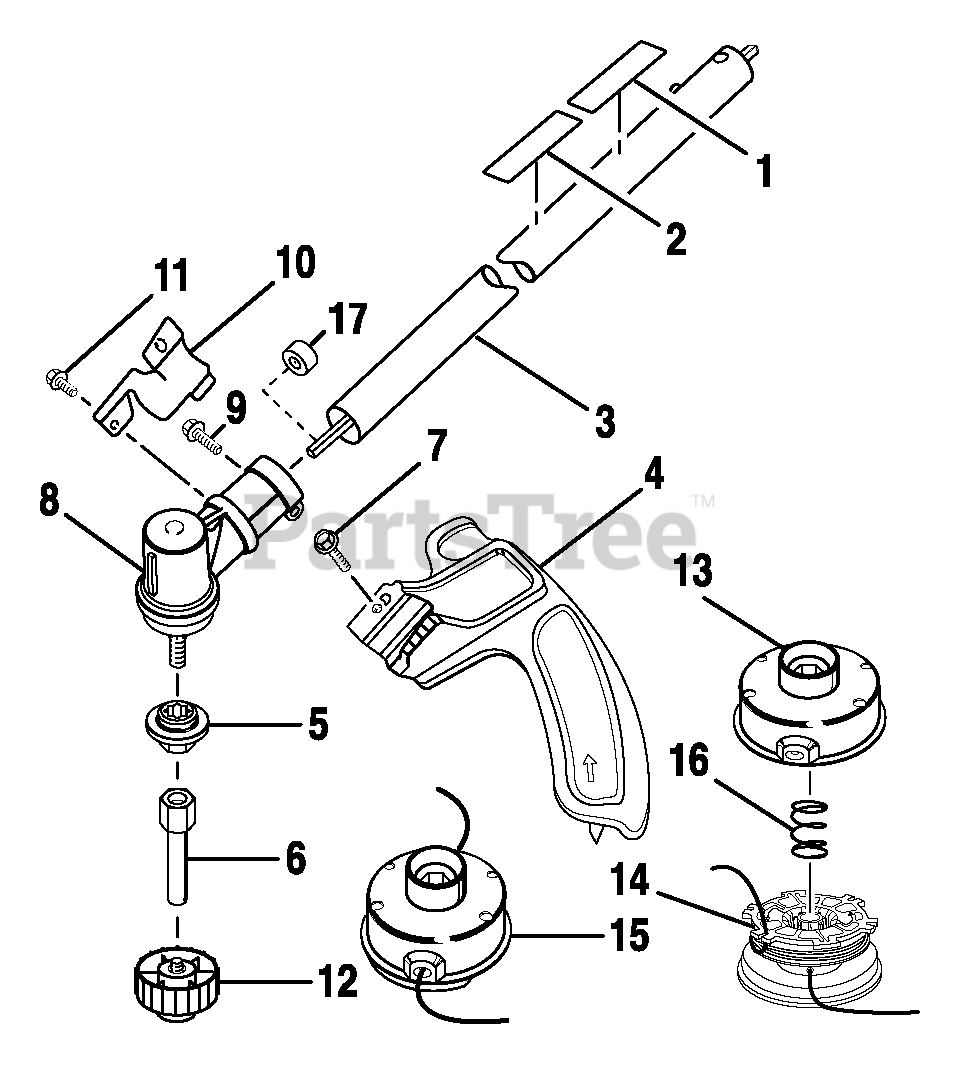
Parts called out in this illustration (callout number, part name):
1	Expand-it Label
2	Warning Decal
3	Straight Shaft Assembly
4	Grass Deflector Assembly
5	Washer
6	Shaft Adapter
7	Screw (1/4-20 x 1-1/4 in.)
8	Gear Head
9	Screw (1/4-20 x 1-1/4 in.)
11	Screw (10-24 x 5/8 in.)
12	Spool Retainer (Red)
13	Housing and Eyelet
14	Spool and String (.095 in.) w/Spring
15	Complete String
17	Spacer
